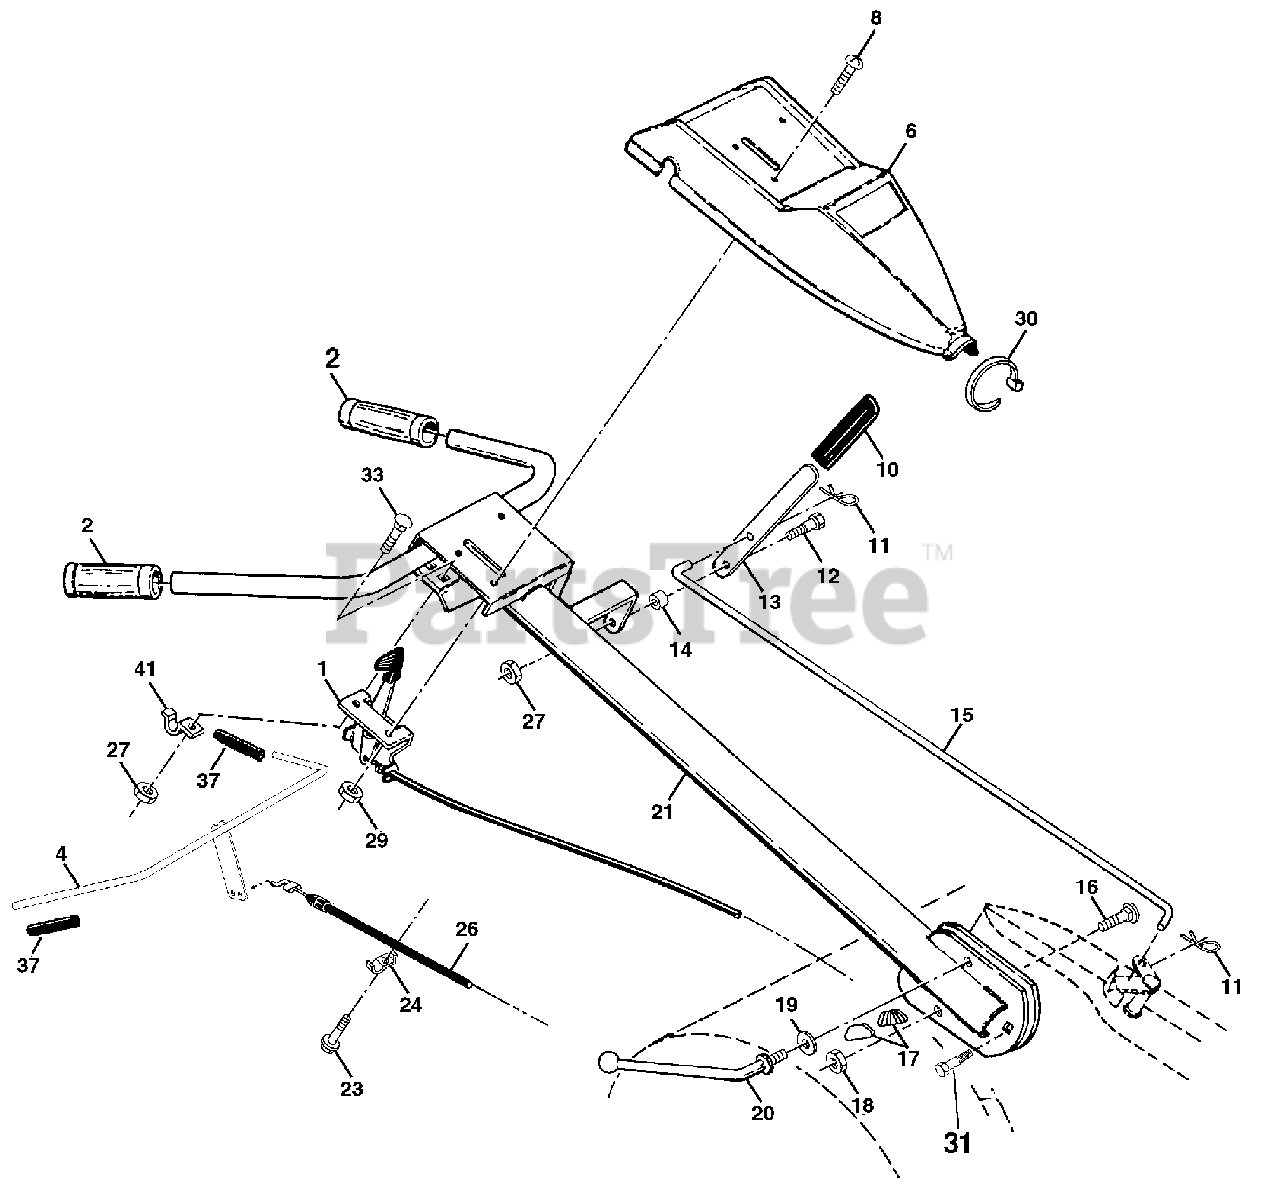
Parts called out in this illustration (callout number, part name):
1	Control, Throttle
2	Grip, Handle
4	Bar Assembly, Control
6	Panel, Control
8	Screw, Phd. #10-24
10	Grip, Handle
11	Clip, Hairpin
12	Bolt, Shoulder
13	Handle, Shift
14	Grommet, Rubber
15	Rod, Shift
16	Bolt, Carriage 3/8-16 x 1 Gr. 5
17	Lock, Handle
18	Nut Crownlock 3/8-16 UNC
19	Washer 13/32 x 1 x 11 Ga.
20	Lever, Lock, Handle
23	Screw Hex Wsh Slt #10-24 x .50
24	Clip
26	Cable, Clutch
27	Nut, Hex Flange 1/4-20 UNC
29	Nut, Keps #10-24 UNC
30	Tie, Cable
31	Bolt, Pivot
33	Bolt, Carriage 1/4-20 UNC x 1/2
37	Grip, Bar, Control
41	Clamp, Bar, Control
